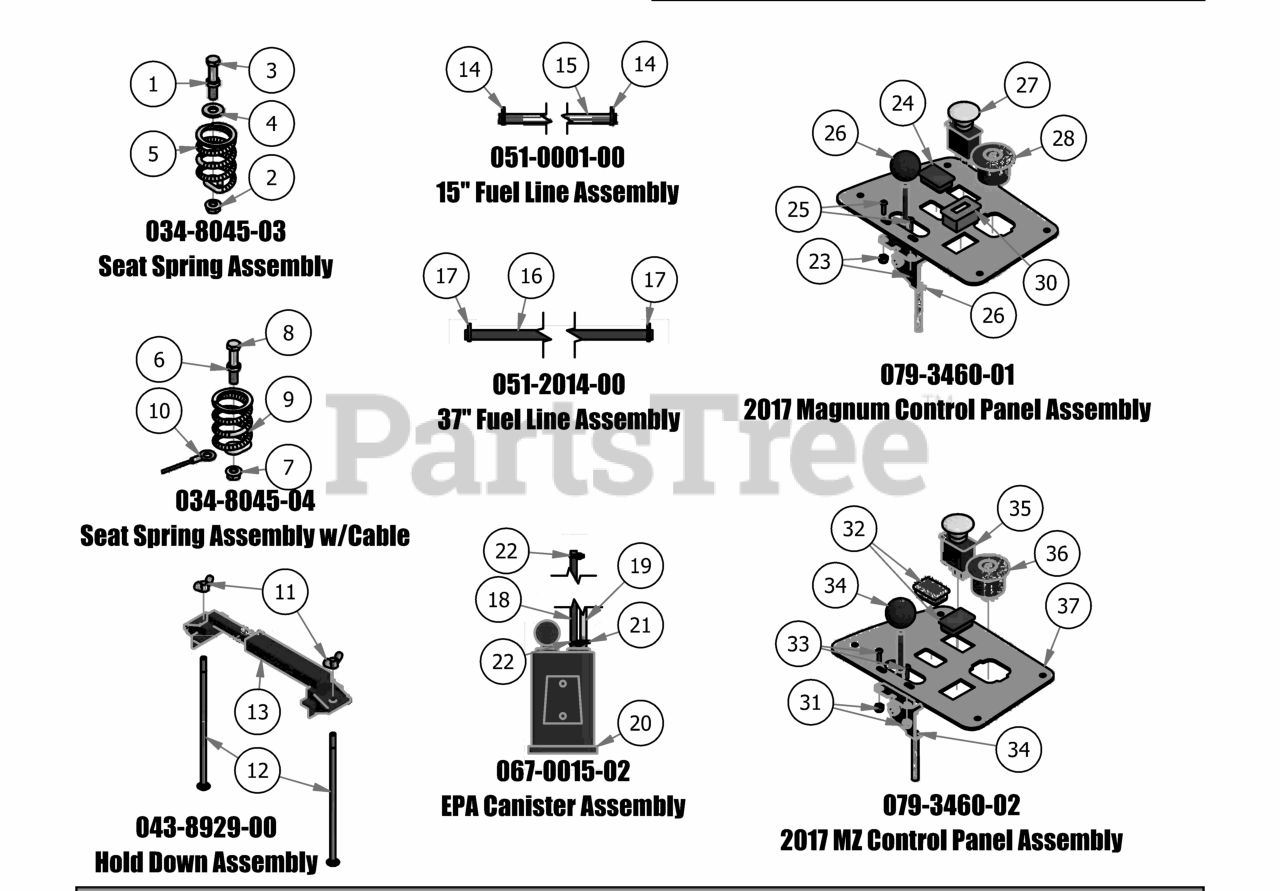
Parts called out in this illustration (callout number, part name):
1	3/8-16 Half Jam Nut
2	3/8" Flange Nut
3	3/8"-16 x 2" Gr 5 Hex Bolt
4	3/8" Flat Washer
5	Seat Spring
6	3/8-16 Half Jam Nut
7	3/8" Flange Nut
8	3/8"-16 x 2" Gr 5 Hex Bolt
9	Seat Spring
10	Seat Cable
11	1/4" Wing Nut
12	1/4-20 X 8 Carriage Bolt
13	Battery Hold Down
14	1/4 Fuel Hose Clamp
15	1/4 Fuel Line
16	37" 1/4 Fuel Line
17	1/4 Fuel Hose Clamp
18	3/16 Vinyl Tubing, 53"
19	3/16" Clear Vinyl Tubing, 44"
20	Carbon Canister for Magnum/MZ
21	3/16" Vinyl Hose Clamp
22	8.6mm Hose Clamp
23	10-24 Nylon Insert Locknut Zinc Orange Nylon
24	Light Plug
25	10-24 X 5/8 BS Button Head Bolt
26	Throttle Lever Assembly
27	PTO Engager
28	Ignition Switch
29	Control Panel
30	Tachometer
31	10-24 Nylon Insert Locknut Zinc Orange Nylon
32	Light Plug
33	10-24 X 5/8 BS Button Head Bolt
34	Throttle Lever Assembly
35	PTO Engager
36	Ignition Switch
37	Control Panel
